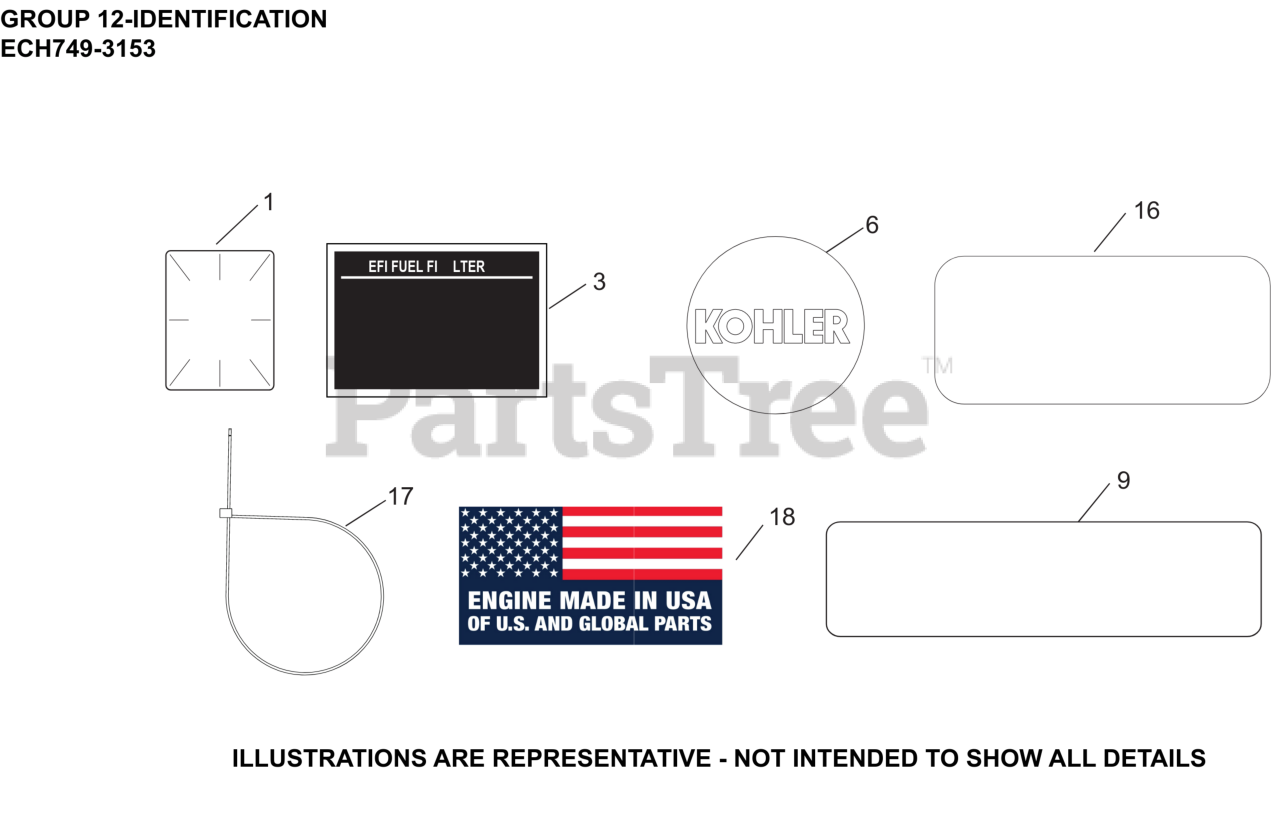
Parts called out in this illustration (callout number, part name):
1	LABEL, CLEAR LAMINATION
3	LABEL, EFI FUEL FILTER
6	LABEL, GRASS SCREEN
9	DECAL LPAC, 26.5 HP/747cc/ECV-ECH749
16	LABEL, CANADIAN COMPLIANCE
18	DECAL, USA
